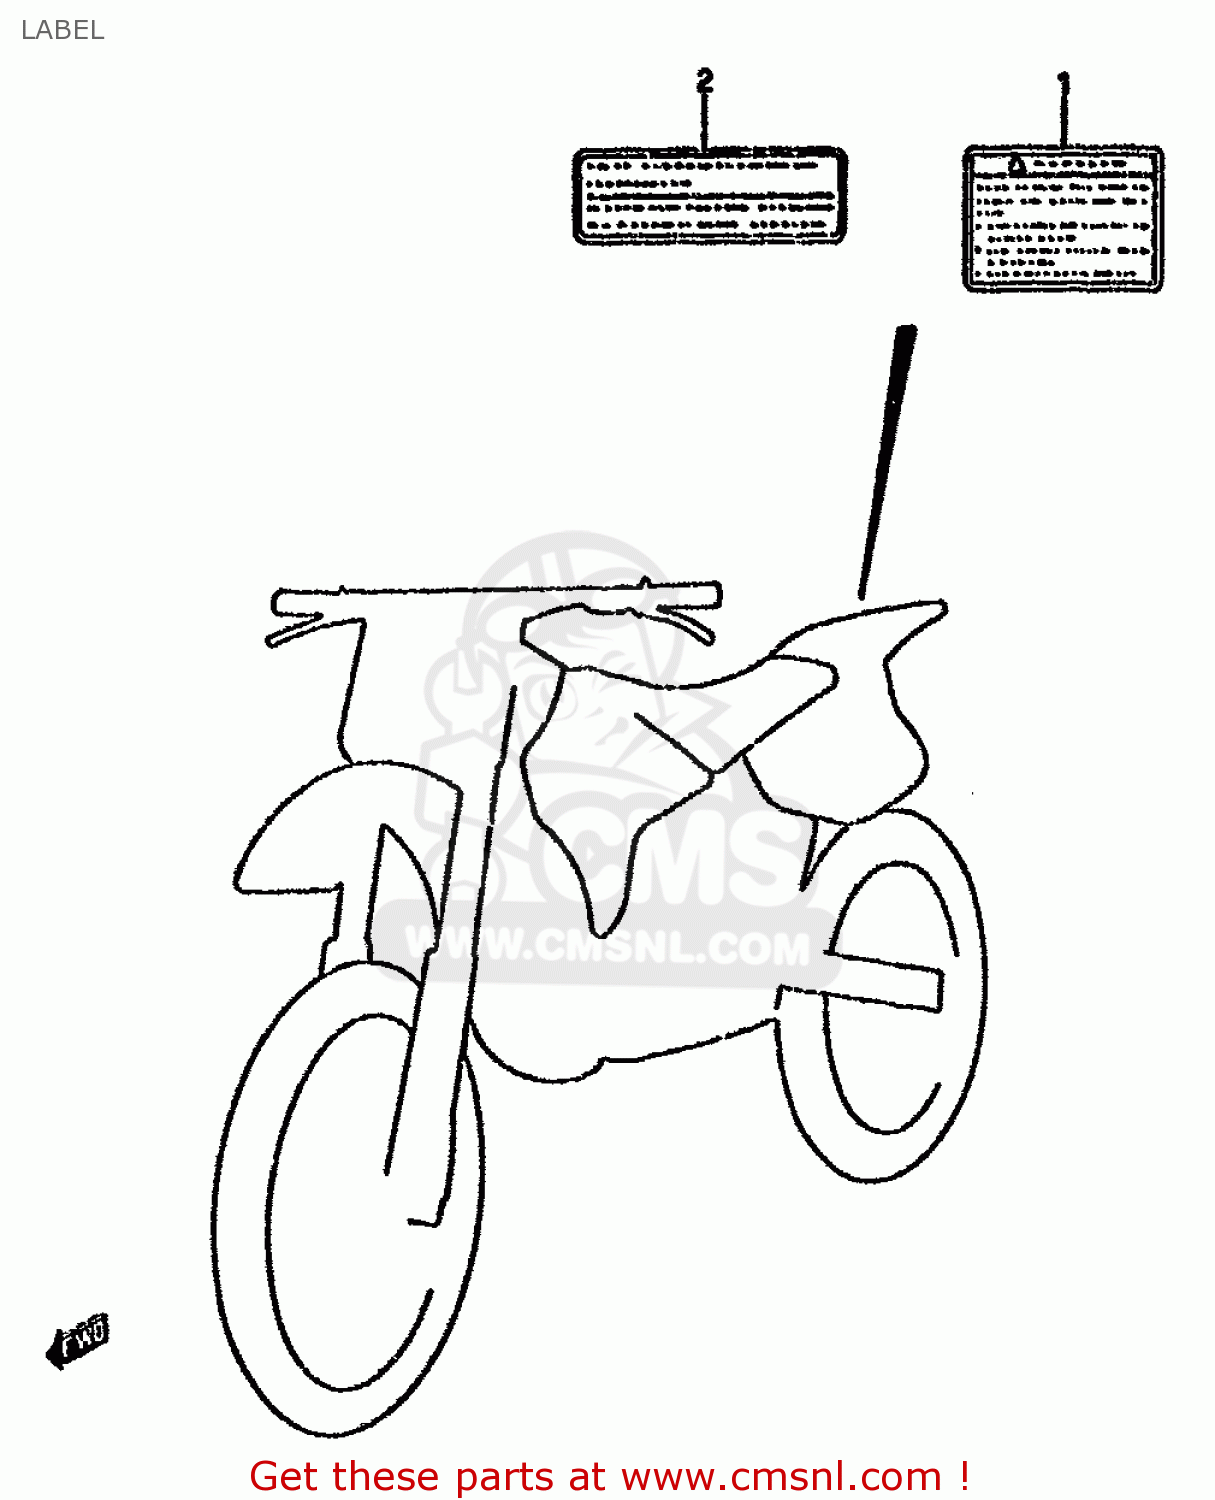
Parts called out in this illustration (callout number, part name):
1	LABEL
2	LABEL,WARNING NO.2
3	MANUAL,OWNER'S
